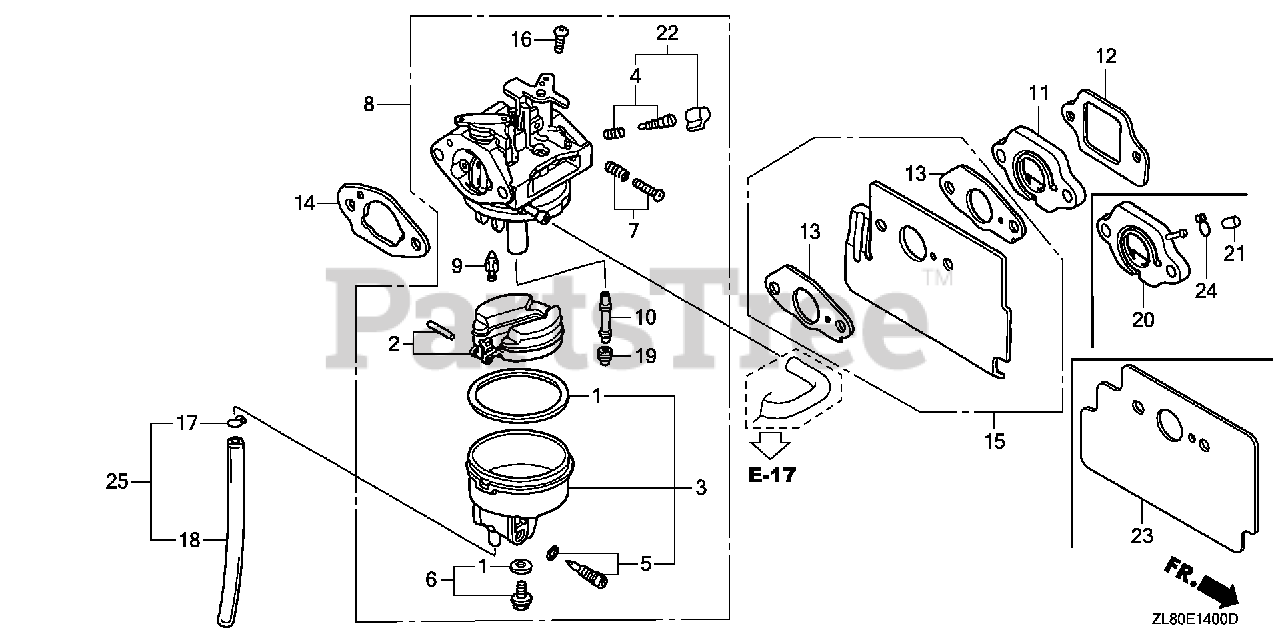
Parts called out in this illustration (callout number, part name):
1	GASKET SET
2	FLOAT SET
3	CHAMBER SET, FLOAT
5	SCREW SET, DRAIN (ADVENTURE GREEN) (CARBURETOR NO.)
6	SCREW SET
7	SCREW SET (THROTTLE STOP) (CARBURETOR NO.)
8	CARBURETOR ASSY. (BB61J B)
9	VALVE, FLOAT (CARBURETOR NO.)
10	NOZZLE, MAIN (CARBURETOR NO.)
11	INSULATOR, CARBURETOR
12	GASKET, INSULATOR
13	GASKET, CARBURETOR
14	GASKET, CARBURETOR (Honda Code 5580253). (CHOKE SIDE)
15	GUIDE, AIR
16	SCREW, PAN (5X6)
17	CLIP, TUBE (B6.5)
18	BULK HOSE, VINYL (4X7X8000) (95003-07(95003-07001-60M) (CARBURETOR NO.)
19	JET, MAIN (#60) (Honda Code 0635474). (CARBURETOR NO.)
19	JET, MAIN (#62) (Honda Code 0635482). (CARBURETOR NO.)
19	JET, MAIN (#65) Use up to Engine SN BB30A D.
22	SCREW SET (CARBURETOR NO.)
